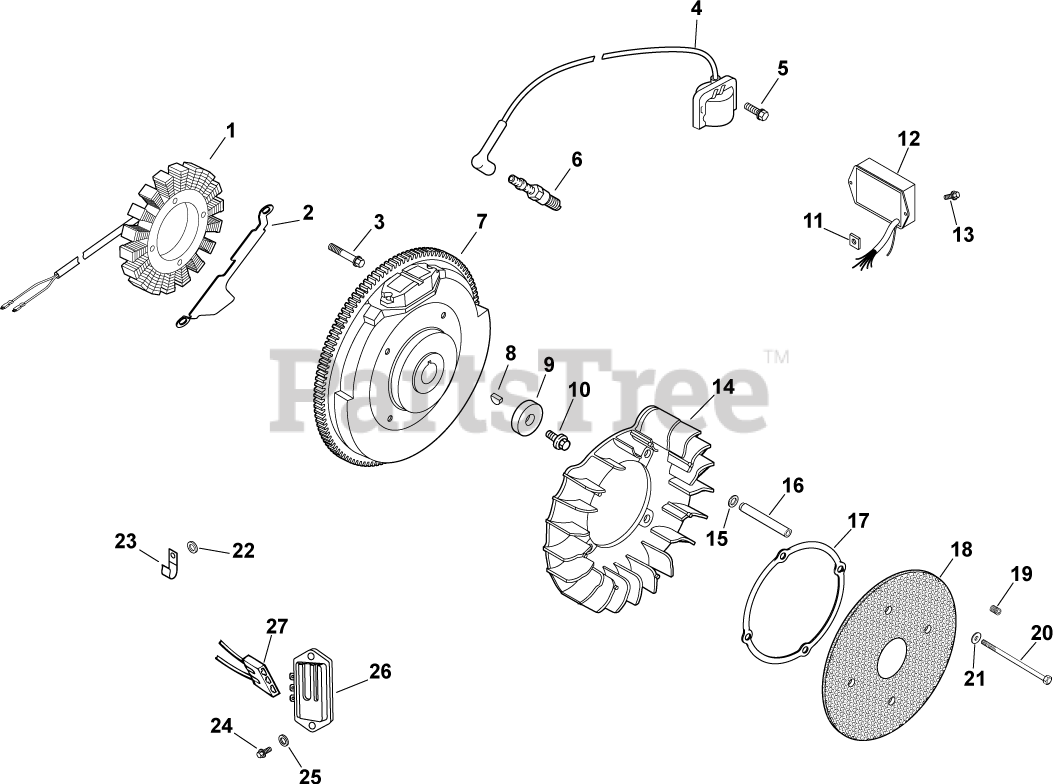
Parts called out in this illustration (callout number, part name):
1	KIT, 15 / 20 AMP STATOR
2	BRACKET, STATOR WIRE
3	SCREW, M5X0.8X25 - (#25086402S)
4	MODULE, IGNITION
5	SCREW, SKT THD FRM M5X0.8X25
6	PLUG, SPARK (PRO SERIES)
7	FLYWHEEL ASSEMBLY - USE 24 025 14-S
8	KEY, 3/16" X 5/8"
9	WASHER, FLAT 13/32"
10	SCREW, FLG M10X1.5X45 - (#25086361S)
11	NUT, PLASTIC
12	MODULE, SPEED ADVANCE
13	SCREW, PHL HD #11-16X1/2"
14	FAN USE 24 157 11-S
15	WASHER, SPRING 10 MM
17	RING, SUPPORT USE 25 141 08-S
18	SCREEN, GRASS
19	SCREW, SKT SET #10-24X1/4"
20	SCREW, CAP M6X1.0X99.5
21	WASHER, FLAT 1/4" (O.D. 5/8")
22	WASHER, FLAT 1/4" (O.D. 1/2")
23	CLIP, CABLE
24	SCREW, PHL HD #11-16X7/8"
25	WASHER, FLAT 3/16"
26	REG/RECT-15 AMP (KM)-USE 41 403 10-S
27	CONNECTOR
